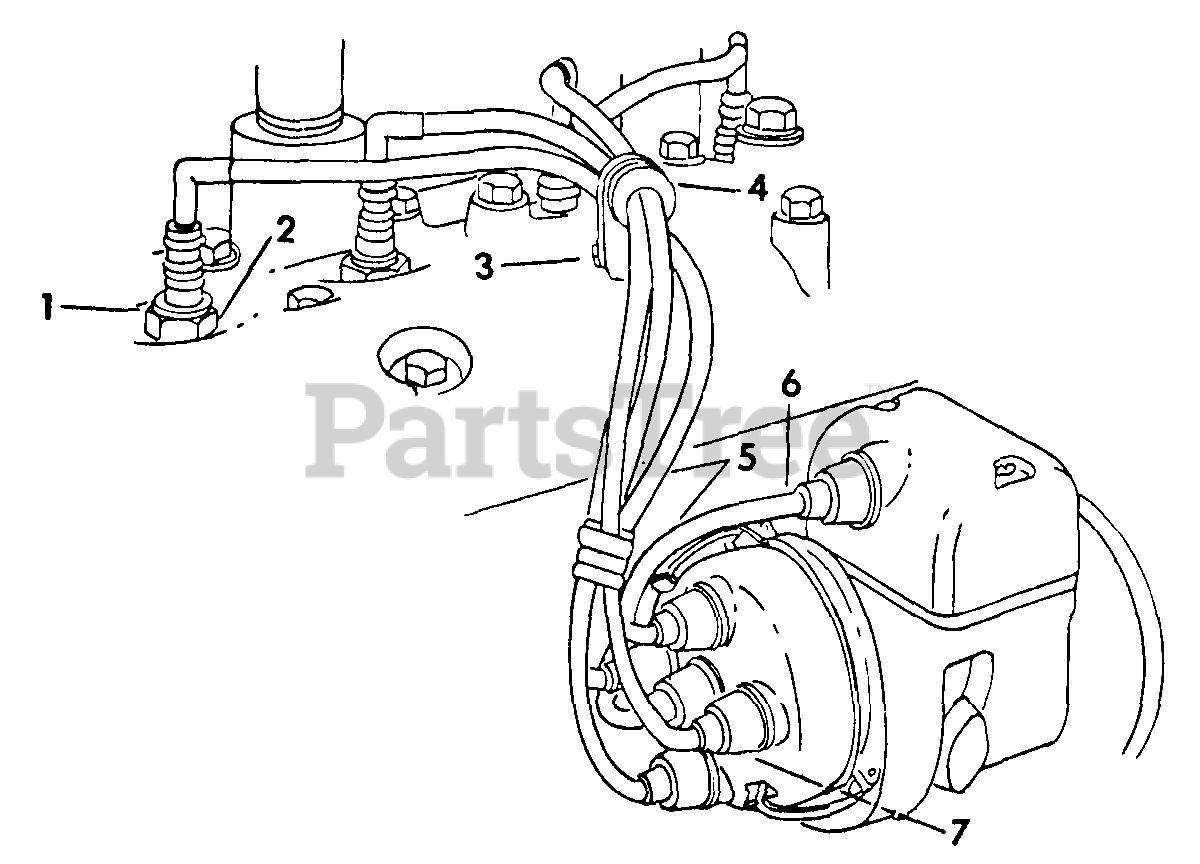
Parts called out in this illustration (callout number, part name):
1	PLUG, SPARK LIGHT SERVICE CHAMPION
2	GASKET, SPARK PLUG
3	BRACKET, SPARK PLUG CABLE
4	GROMMET, SPARK PLUG CABLE BRACKET
5	PACKAGE, IGNITION CABLE SERVICE
6	CABLE, COIL TO DISTRIBUTOR W/NIPPLES
7	NIPPLE, DISTRIBUTOR CAP TERMINAL
